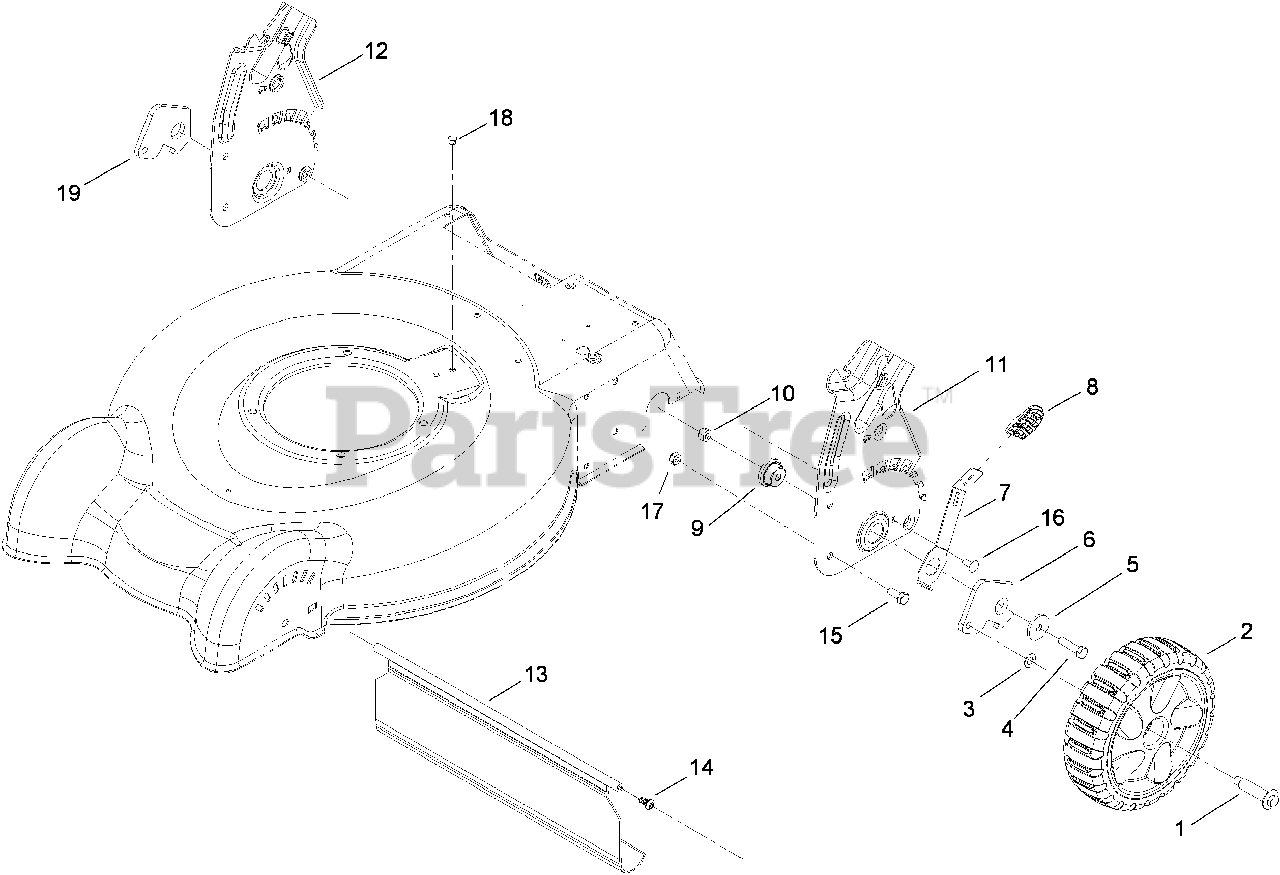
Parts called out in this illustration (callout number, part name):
1	BOLT-SHOULDER
2	8 INCH WHEEL ASM
4	SCREW-HH
5	Washer-Flat
6	Arm-Pivot, Rear
7	Arm-Spring
8	Knob-Lever, HOC
9	Bushing-Mount, HOC
10	NUT-LOCK, NI
11	PLATE-HOC, LH
12	PLATE-HOC, RH
13	SHIELD-TRAILING
14	SCREW-PTH
15	SCREW-HH
16	SCREW-CARR
17	NUT-LOCK, NI
18	Plug-Dome
19	ARM-PIVOT, REAR (RH)
